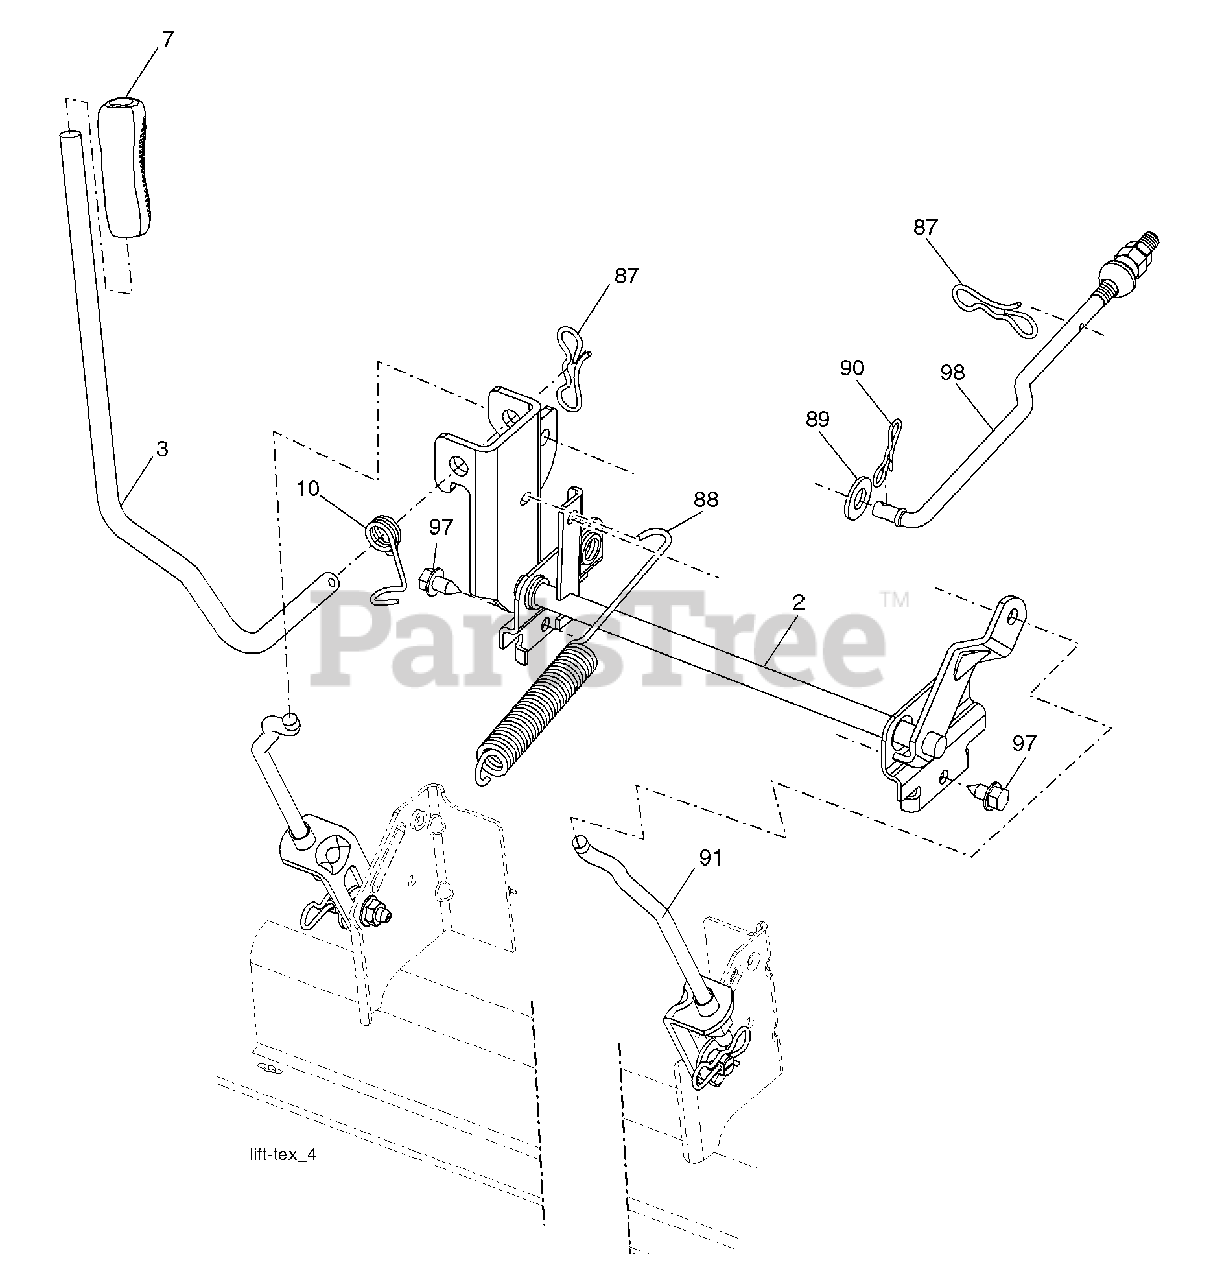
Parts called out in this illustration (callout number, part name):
2	Shaft Asm., Lift
3	Lever Asm., Lift Rh
7	Grip, Lever
10	Spring Torsion
87	Pin Cotter 7/16 Bow Tie Lock
88	Spring Lift Assist
89	Washer Clear Zinc
90	Pin Cotter 5/16 Bow Tie Lock
91	Link Lift Susp Mower Rear
97	Screw 3/8-16 x .75 Smgml Tap/R.Z
98	Link Lift Susp. Front Mower
